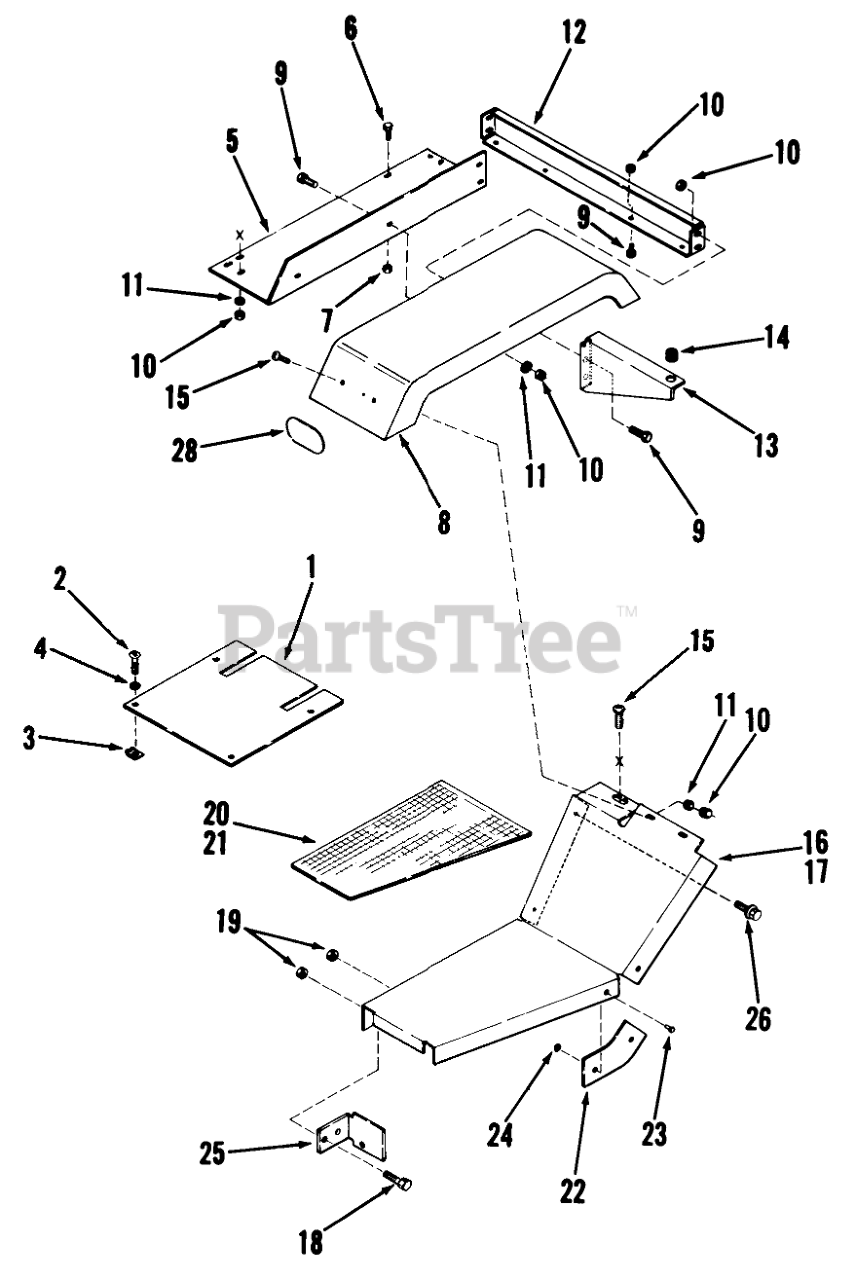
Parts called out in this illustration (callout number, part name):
1	Access Cover Plate
2	Screw-Hex HD Slotted
3	Speed Nut
4	LOCKWASHER
5	Plate-Fender RH
5	Plate-Fender LH
6	Bolt
7	Nut
8	Fender
9	Bolt
10	Nut
11	WASHER 5/16 SAE
12	Channel
13	Wear Plate
14	GROMMET
15	Screw
16	Footrest RH
17	Footrest LH
18	BOLT
19	Nut
20	Footrest Mat RH
21	Footrest Mat LH
22	Filler Plate
23	RIVET
24	WASHER
25	Bracket
28	Reflector
